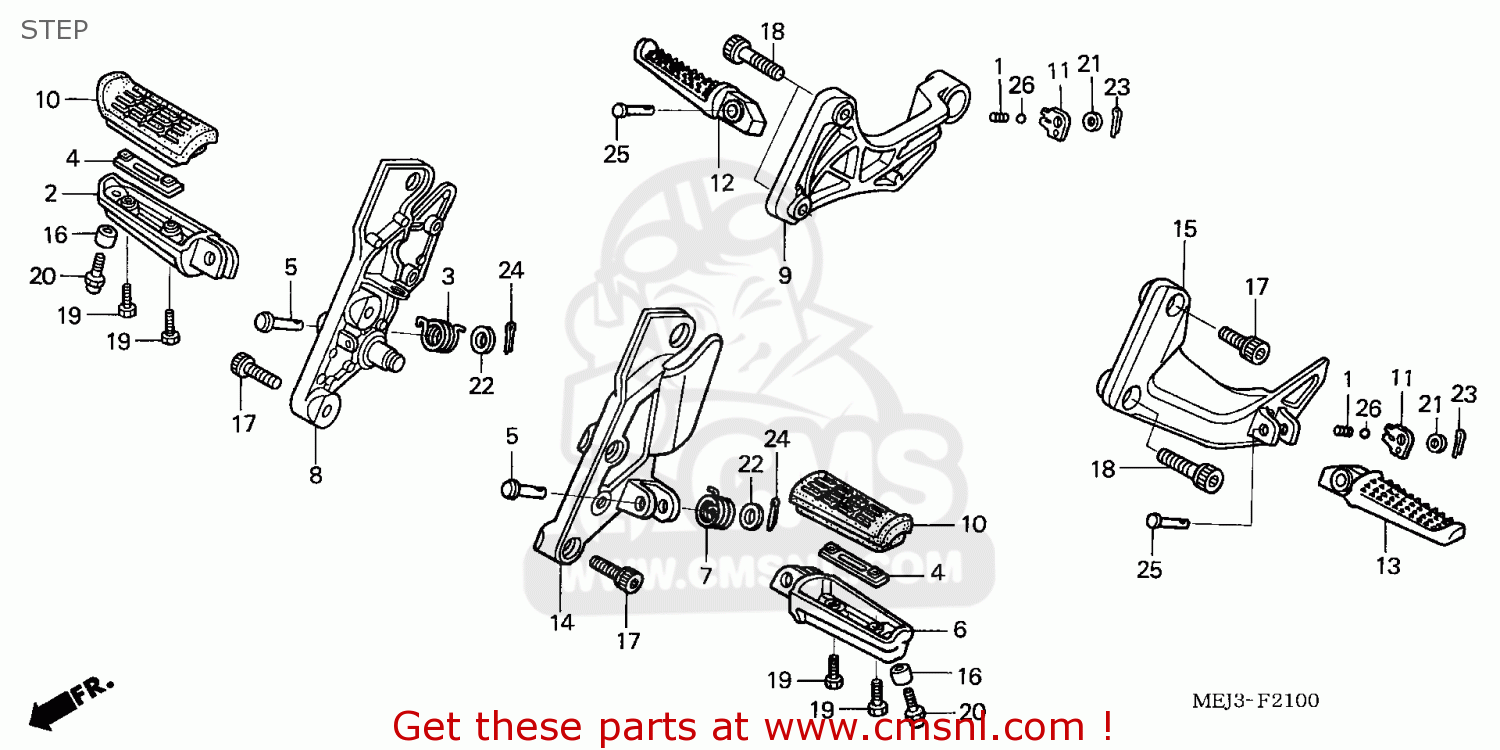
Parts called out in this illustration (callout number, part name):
1	SPRING KICK
2	ARM R STEP
3	SPG,R STEP RETURN
4	PLATE,STEP SET
5	PIN,STEP BAR
6	ARM ,L STEP
7	SPG.L STEP RETURN
8	HOLDER,R STEP
9	HOLDER R,P.STEP
10	RUBBER,STEP
11	PLATE,PILLION STE
12	ARM,R P,STEP
13	ARM,L P,STEP
14	HOLDER L,STEP
15	HOLDER L,P.STEP
16	COLLAR,TOP BRIDGE
17	BOLT,SOC.,8X28
18	BOLT,SOCKET 8X34
19	BOLT,MAIN STEP RU
20	BOLT,CAP,8X25
21	WASHER,PLAIN, 6MM
22	WASHER,8MM
23	PIN,SPLIT, 1.6
24	PIN,COTTER 2.0X15
25	PIN C,PILLION
26	BALL,STEEL.,8
